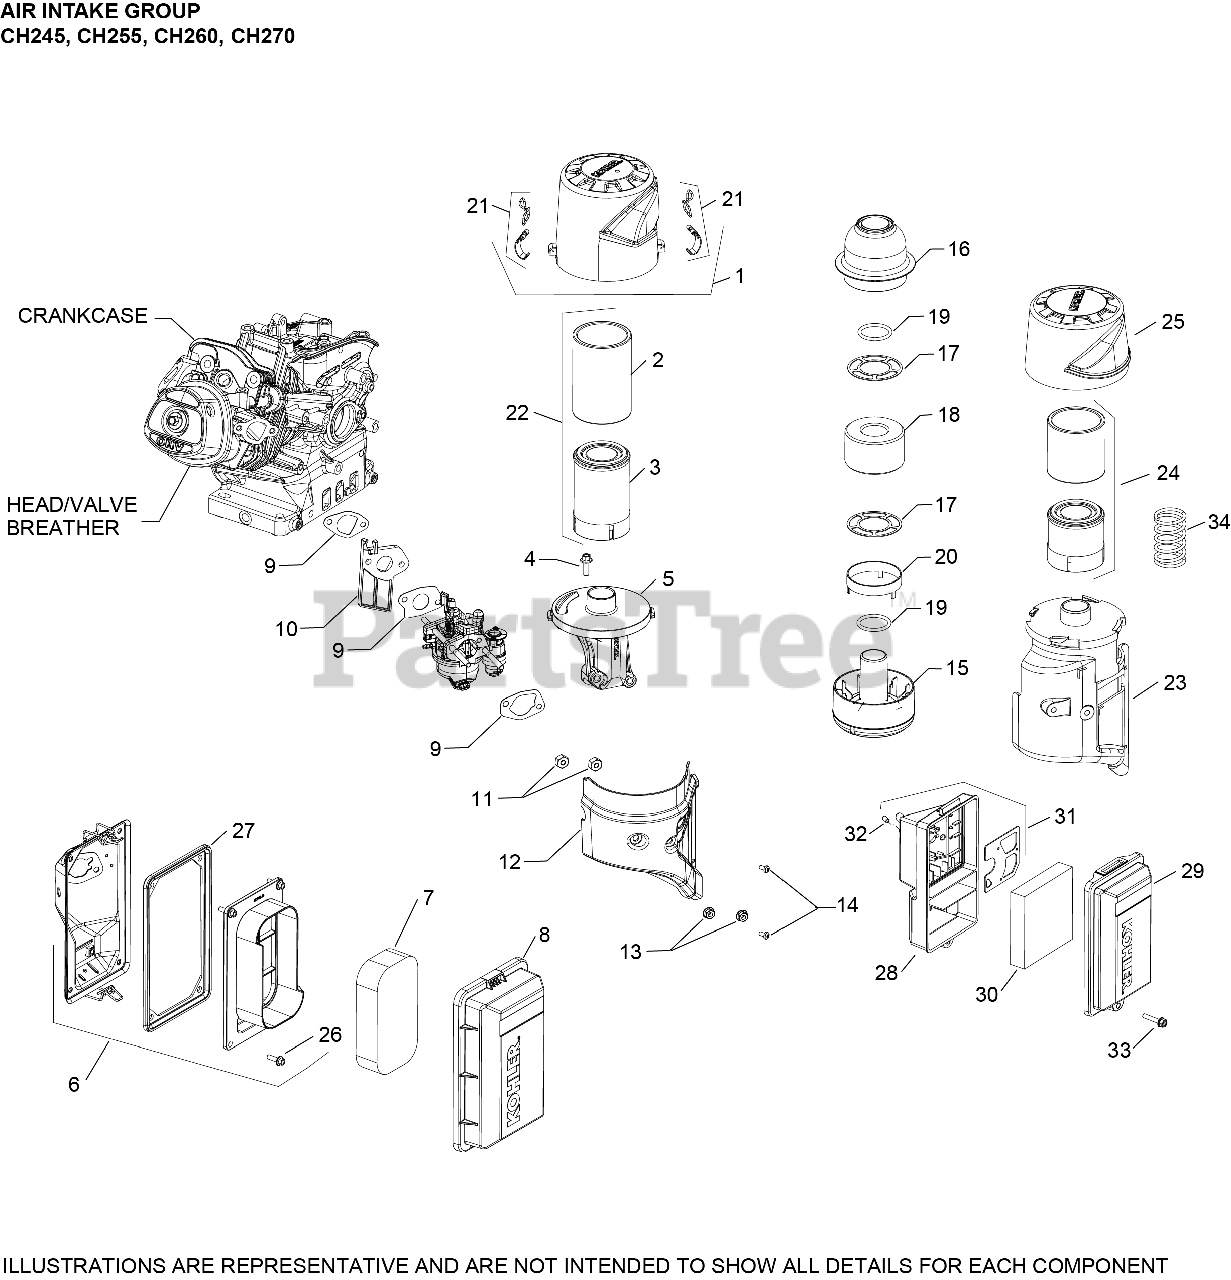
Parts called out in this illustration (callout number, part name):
13	NUT, HEX FLANGE LOCK (M6)
23	BASE, AIR CLEANER ASSEMBLY
24	ELEMENT, FILTER ASSEMBLY
25	COVER, AIR CLEANER ASSEMBLY
